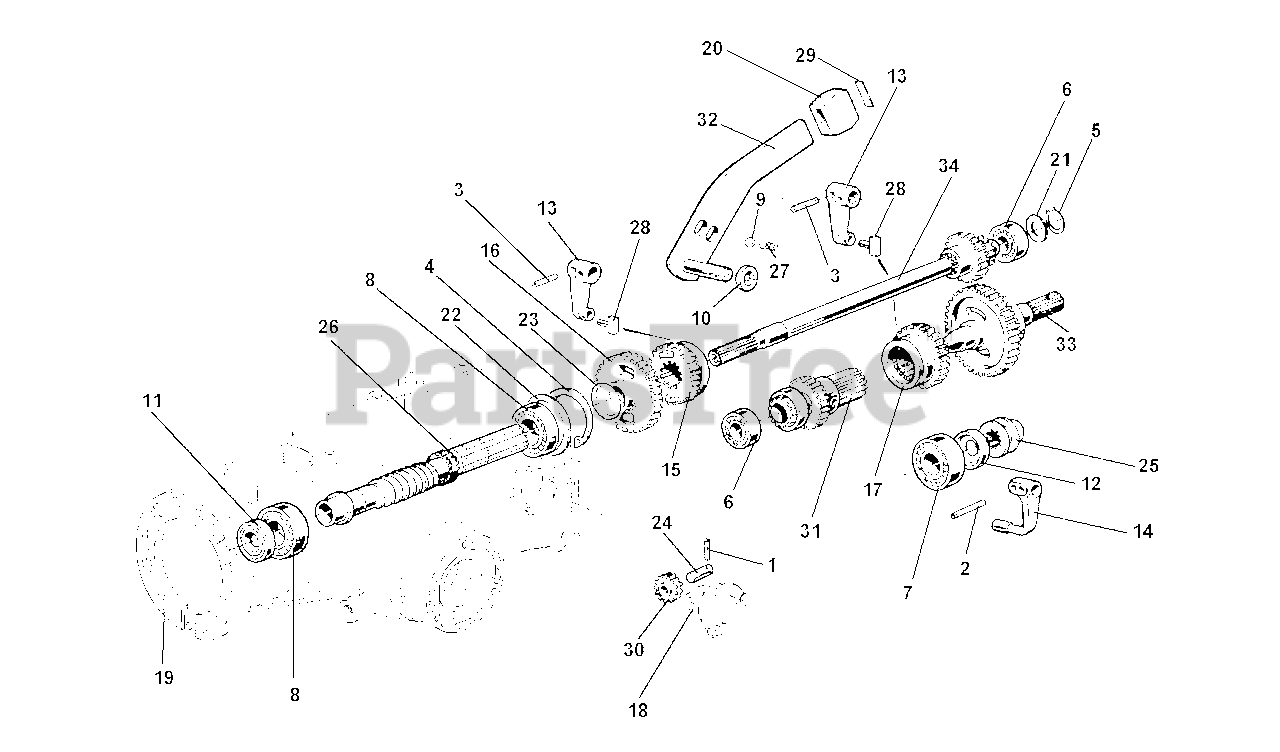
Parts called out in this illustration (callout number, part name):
1	PIN, LOCKING 2.5 X 22 DIN 1481
2	LOCKING PIN 4 X 20 SPIRAL
3	LOCKING PIN 4 X 24 SPIRAL
4	CIRCLIP, INTERN D 52
6	BEARING 15 X 35 X 11 6202
7	BEARING 20 X 47 X 14 6204
9	BALL 15/32 RIV RB-11.906
10	SEAL, OIL 12 X 19 X 5 STANDARD
11	SEAL, OIL 15 X 40 X 10 STANDARD
12	SEAL, OIL 20 X 35 X 7 STANDARD
13	LEVER, SPEED CHG SLDG GR
14	SLIDE LEVER
15	SLIDER SPEEDS
16	WHEELS FIRST SPEED
17	REDUCTION UNIT SLIDER
18	FLANGE, REVERSE SPEED
19	CASING 5 SPEEDS GEARBOX
20	KNOB REDUCTION UNIT LEVER
21	WASHER 15.1 X 25 X 2
22	RING C - 72
23	WASHER 25 X 32 X 2 C - 72
29	PLATE SLOW/FAST SPEEDS
30	REVERSE SPEED GEAR
31	GEAR TRIPLE
32	LEVER REDUCTION UNIT
33	P.T.O. SHAFT
34	CLUTCH SHAFT
